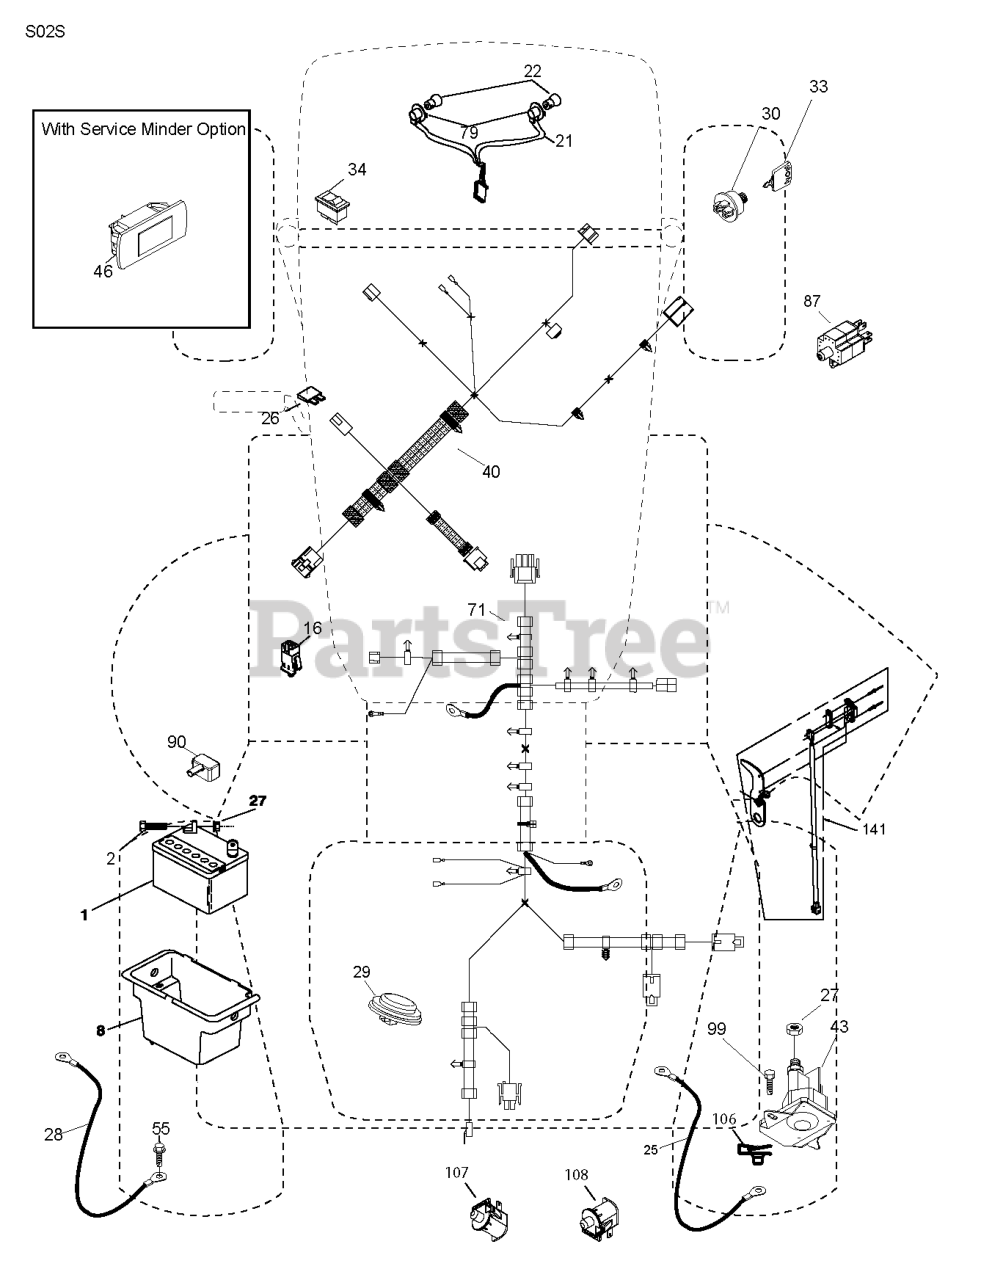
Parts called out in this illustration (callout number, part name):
1	REPL BY 532 12 38-99
2	BOLT.HEX.1/4.X.3/4.DICHROMATE
8	BOX.BATTERY.LT/SRD
16	SWITCH INTERLOOK PUSH-IN
21	HARNESS.LIGHT W/4152J BULBS
25	CABLE.BATTERY.20.RED.8 AWG
26	FUSE 20AMP
27	NUT
28	CABLE.GROUND.REAR.BATTERY.8G
29	SWITCH.SEAT.DELTA.OPC.
30	SWITCH.IGN.DELTA.W.LGH.ROS
33	KEY.CHAIN.BLISTER.PACK.GEN.INT
40	RP HARNESS.ELECTRICAL.DASH.SRD
43	SOLENOID.W/BRASS.PLUNGER
55	SCREW 5/16"
71	RP.HARNESS.ELEC.CHASSIS.SRD
79	BULB HOLDER ASM.
87	RP SWITCH.RAILMOUNT.NO-NC-NC
90	COVER, TERMINAL BATTERY
99	SCREW HEXWSHR 1/4-20X3/4
106	1/4-20 U NUT
107	SWITCH.SNAPMOUNT.NO.#2
108	SWITCH.SNAPMOUNT.NC
141	KIT T2.ROS 71677
